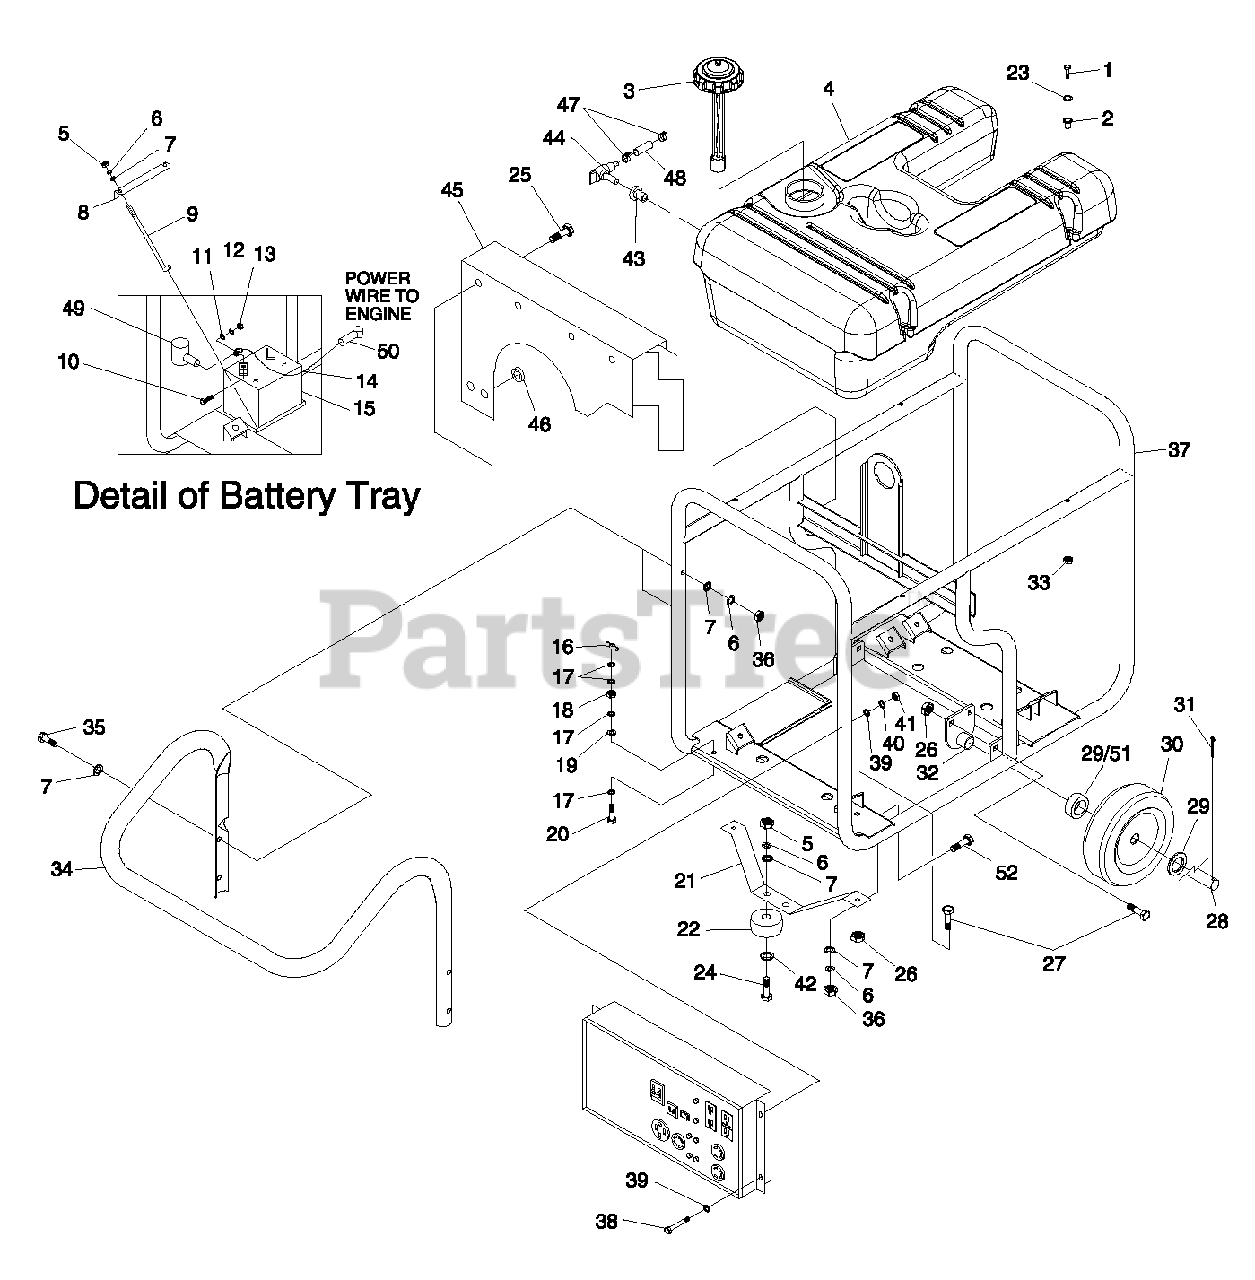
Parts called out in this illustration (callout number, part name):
1	SCREW HHC M6-1.0 X 55
2	RUBBER TANK MOUNT
3	CAP, FUEL WITH GAUGE & VENT
4	KIT, FUEL TANK
5	NUT HEX M8-1.25
6	WASHER LOCK M8-5/16
7	WASHER FLAT 5/16
8	BRACKET BATTERY
9	BOLT,BATTERY J-BOLT
10	SCREW HHC 1/4-20 X 3/4 G5
11	WASHER FLAT 1/4
12	WASHER LOCK M6-1/4
13	NUT HEX 1/4-20
14	BATTERY CABLE, RED
15	BATTERY U1
16	NUT WING 5/16-18 BRASS
17	WASHER FLAT 5/16 BRASS
18	NUT HEX 5/16-18 BRASS
19	5/16 SPECIAL L/WASH
20	SCREW HHC 5/16-18 X 1.5 BRASS
21	BRACKET FRONT FOOT (15 kW)
22	VIB MOUNT
23	WASHER FLAT .25ID X 1"OD
24	SCREW HHC M8-1.25 X 30
25	SCREW HHTT M6-1.0 X 12
26	NUT LOCK FL 3/8-16
27	BOLT CARR 3/8-16 X 1
28	AXLE, 3/4"DIA X 30" (15 kW)
29	WASHER FLAT 3/4" (15 kW)
30	12.3" PNEUM WHEEL 3/4" AXLE (15 kW)
31	PIN COTTER 1/8 X 1-1/4
32	BRACKET, WHEEL SPACER
33	NUT FLANGE M6-1.0 NYLOK
35	SCREW HHC 5/16-18 X 2-1/2 G5
36	NUT LOCK HEX 5/16-18 NYLON INSERT
37	FRAME
38	SCREW HHC M5-0.8 X 45 G8.8
39	WASHER FLAT M5
40	WASHER LOCK M5
41	NUT HEX M5-0.8
42	WASHER FLAT 1"
43	BUSHING TANK DEXTOR
44	VALVE, PLASTIC TANK
45	AIR DEFLECTOR
46	GROMMET .75 X .06 X .50
47	CLAMP HOSE BAND1/4
48	HOSE1/4 ID
49	BOOT BATTERY CABLE
50	BOOT STARTER CABLE
51	SPACER, AXLE (15 kW)
52	SCREW HHC 5/16"-18 X 1"
